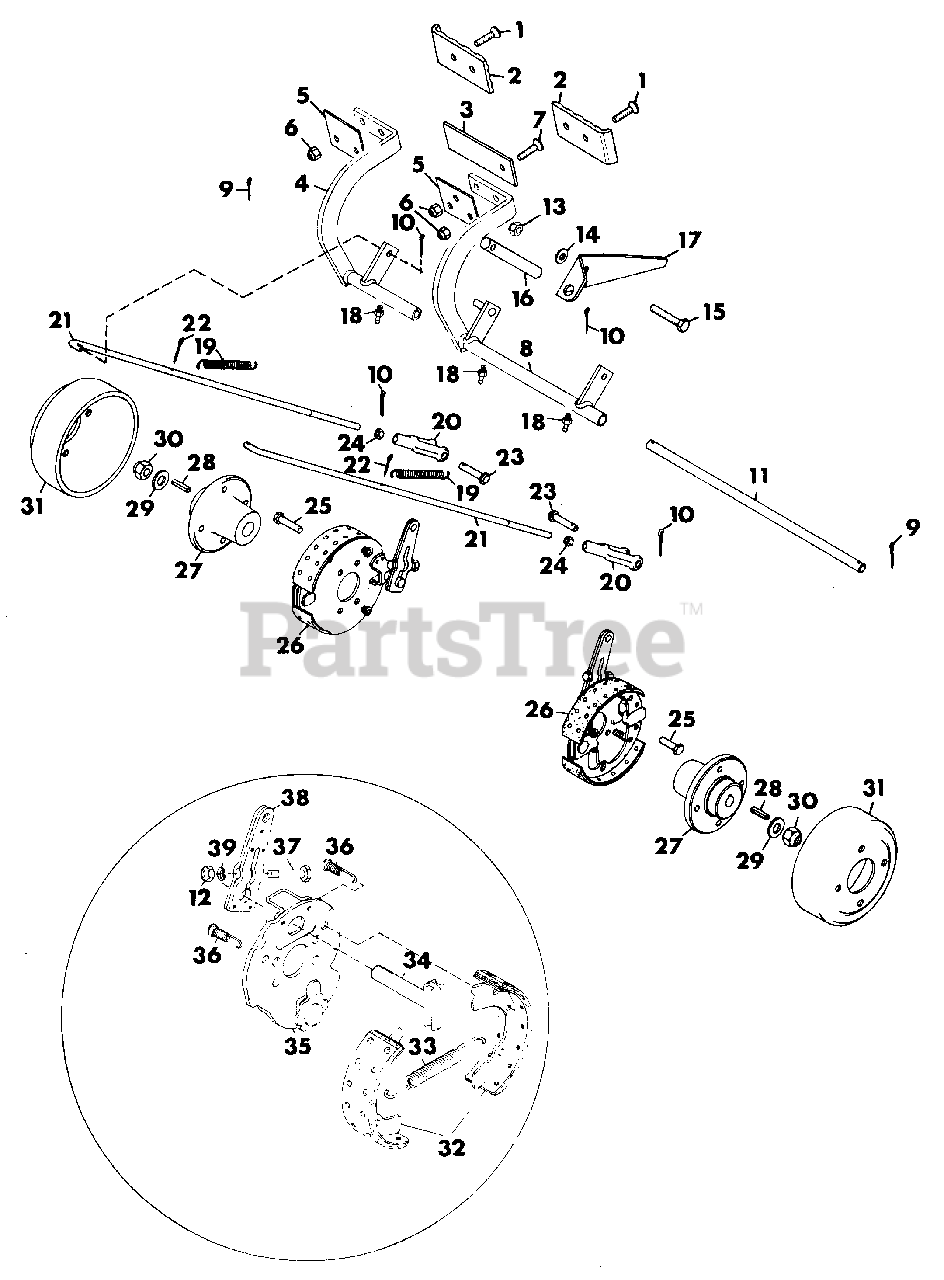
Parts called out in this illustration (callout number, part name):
1	SCREW, MACHINE 1/4-20X1.25
2	PEDAL, BRAKE
3	ARM, BRAKE LOCK
4	PEDAL, BRAKE
5	PLATE, BRAKE LOCK BACKING
6	NUT, LOCK 1/4-20
7	SCREW, MACHINE 1/4-20X1.0
8	PEDAL, BRAKE
9	PIN, COTTER .125X1.25
10	PIN, COTTER .09X.625
11	SHAFT, BRAKE
12	NUT, HEX 5/16-24
13	NUT, LOCK 3/8-16
14	WASHER, NYLON .375X.75X.060
15	BOLT, HEX 3/8-16X2.25
16	ROD
17	LEVER, BRAKE LOCK
18	FITTING, LUBE 1/4-28
19	SPRING, EXTENSION 5.5X.5X20 RATE
20	CLEVIS, 3/8-24 ADJUSTABLE
21	ROD, BRAKE
22	PIN, COTTER .125X.75
23	PIN, CLEVIS .375X.948
24	NUT, JAM 3/8-24 HEX HD
25	BOLT, HEX 3/8-16X.75
26	BRAKE, 7X1.75 MECHANICAL
27	HUB, OFC
28	KEY, HUB .187X1.500
29	WASHER, FLAT .656X1.312X.095
30	NUT, LOCK 5/8-11
31	DRUM, 7X1.75
32	SHOE, BRAKE
33	SPRING, SHOE RETURN
34	CAM, BRAKE
35	PLATE, BACK
36	SPRING, SHOE RETAINING
37	BOLT, HEX 5/16-24X1.75
38	ARM, CAM LEVER
39	WASHER, LOCK 5/16 REG.
